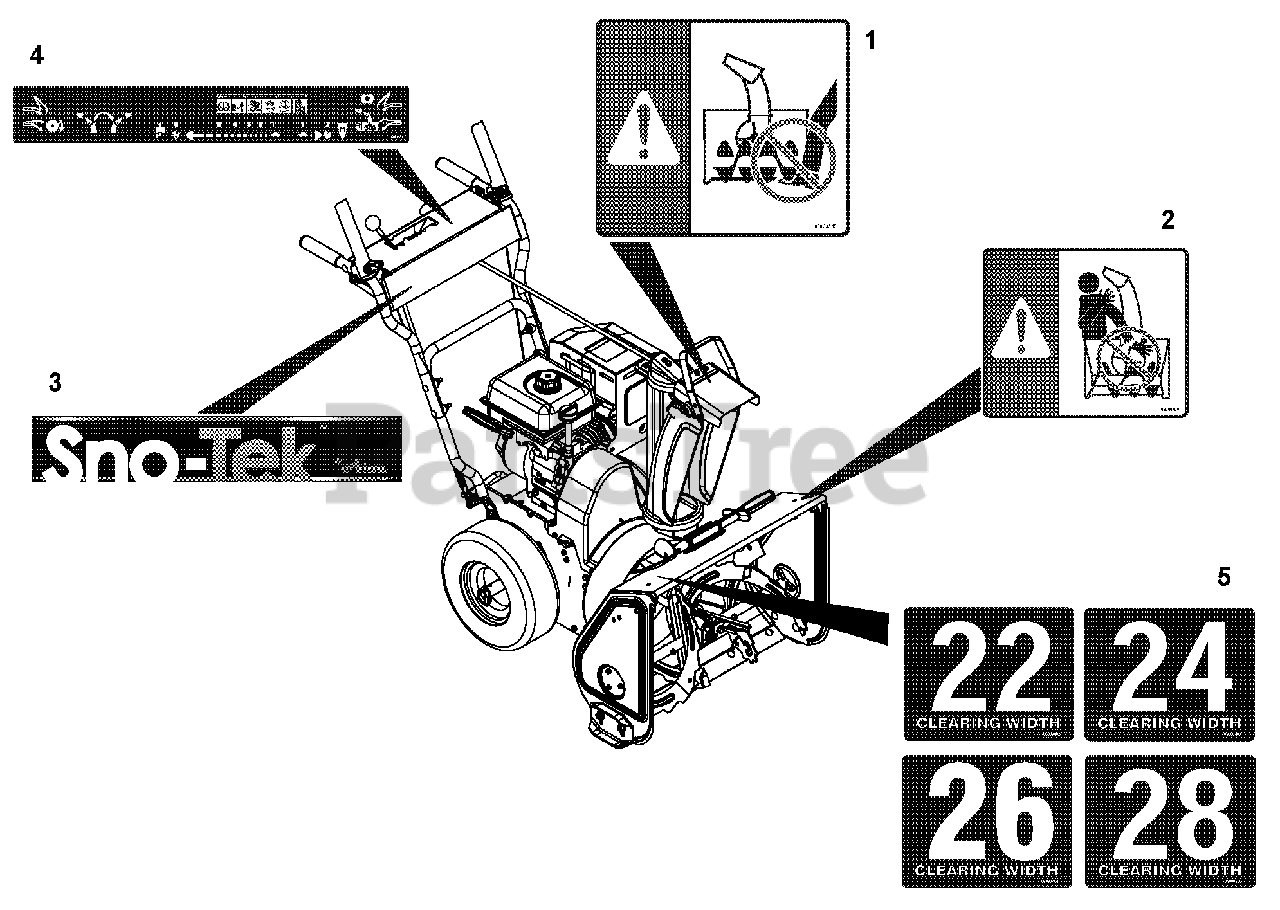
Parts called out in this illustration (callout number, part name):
1	DECAL, DANGER - ROTATING PARTS
2	DECAL, DANGER
3	DECAL, DANGER - ROTATING PARTS
4	DECAL, CONTROL, COMPACT/DELUXE
5	DECAL, HOUSING SNO-TEK 22
